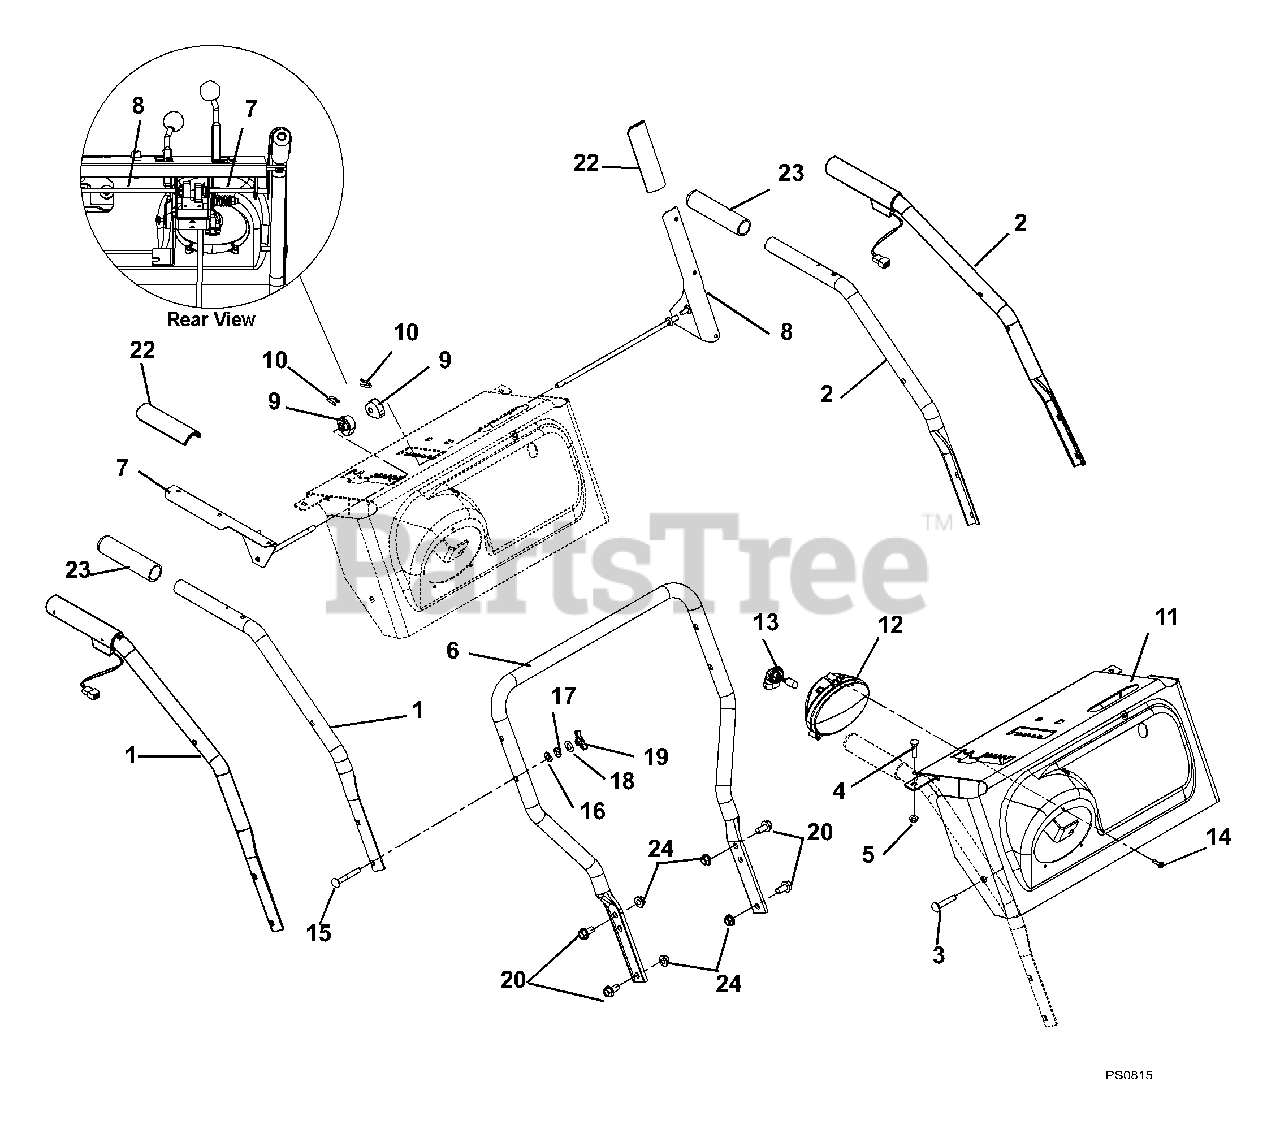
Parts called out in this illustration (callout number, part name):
1	HANDLEBAR, UPPER-RH
1	HANDLEBAR, UPPER RH-W/HW
2	HANDLEBAR, UPPER-LH
2	HANDLEBAR, UPPER LH-W/HW
3	@BLT-RDHDSQNK .31-18X1.75 G5YZ
4	BLT-RDHDXLSQNK.25-20X1.25 G5ZC
5	@NUT-LK-CTR .25-20 YWZC
6	HANDLEBAR, LOWER
7	LEVER, RH-ATTACHMENT
8	LEVER, LH-TRACTION
9	CAM, INTERLOCK
10	PIN, SPRING CLIP
11	PANEL-W/CONTROL DECAL
11	PANEL-W/CONTROL HW DECAL
11	PANEL-W/CONTROL 12V DECAL
11	PANEL-W/CONTROL BRUSH DECAL
12	LIGHT, HALOGEN ASSY.
13	BULB, LIGHT-HALOGEN 20W
14	SCR-TAP 10-16X.75 HI-LO PPH
15	@BLT-RDHDSQNK .31-18X2.25 G5YZ
16	WASHER,SADDLE-.320 X.937 X.062
17	WSHR-LK .312X.097 HVY YWZC
18	@WSHR-FL-STL.38X.875X.083 YWZC
19	KNOB - WING .312-18 UNC
20	BLT-SERHFWH .38-16X.75 YWZC
21	@NUT-LK-TOP-FLG .38-16 YWZC
22	GRIP, CLUTCH LEVER, LH AND RH
23	HANDLE GRIP
24	@NUT-LK-CTR .31-18 YWZC
